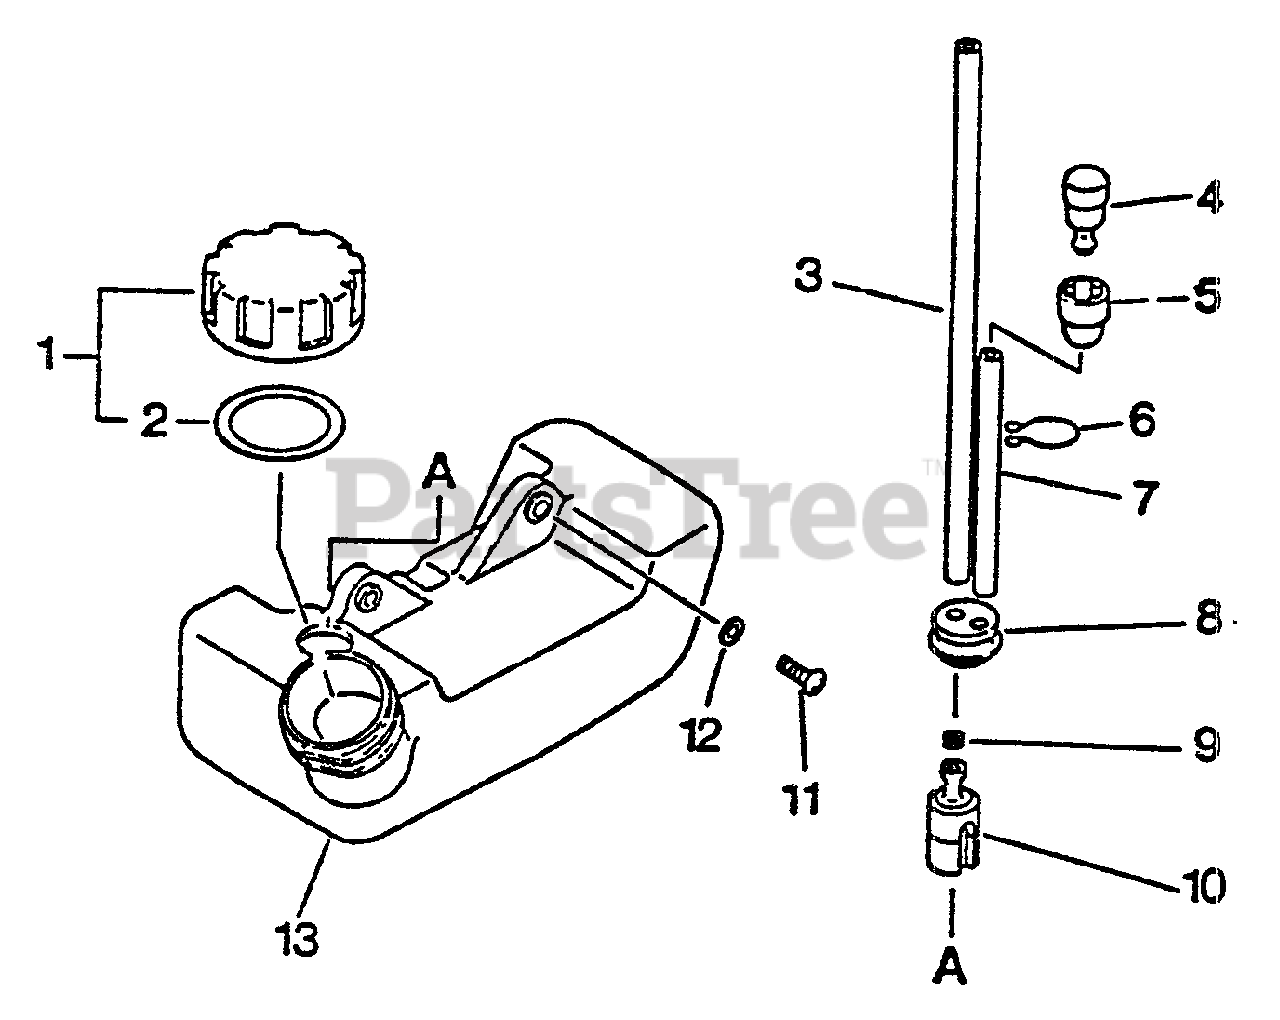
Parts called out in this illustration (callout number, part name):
1	CAP ASSY
2	GASKET, CAP
3	PIPE - 3X5X180 -- BLACK
4	VENT, FUEL TANK
5	COVER, VENT
7	PIPE - 3X6X70 -- CLEAR
8	GROMMET
9	CLIP - 6
10	FILTER, FUEL
11	SCREW - 5X16
12	WASHER - 5
13	TANK, FUEL
